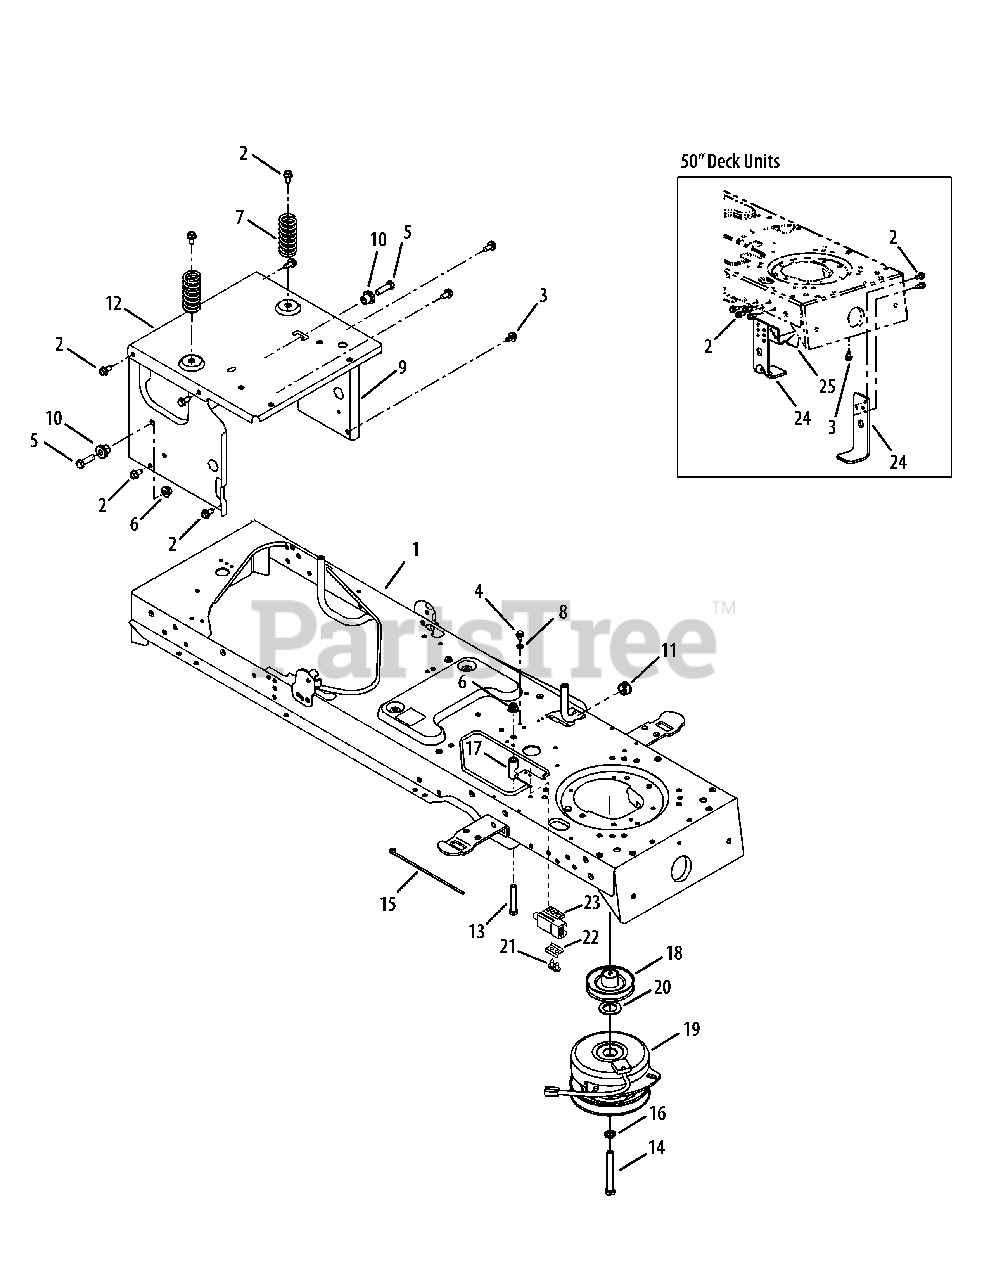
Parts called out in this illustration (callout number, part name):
3	Screw, Hex Wash. Tapp, 5/16-18 x .5
4	Screw, Hex Wash. Hd. Tapp, 1/4-20 x 0.625
5	Hex Screw 3/8-16 x 1.25
6	Nut, Nylon Lock, 3/8-16
7	Spring, Compression, 1.28 OD x 3.125
8	Washer, Lock, Ext. 1/4
11	Snap Bushing
13	Screw, 3/8-16 x 2.25 GR5
14	Screw, Hex Cap , 7/16-20 x 3.5 GR5
15	Cable, Tie, 3/16 x .05 x 7.4
16	Washer, Lock, 7/16, Regular Duty
17	Spacer, 3/8 x 1.54
18	Electric PTO Engine Pulley
19	Clutch, PTO
20	Washer, Flat, 1.031 x 1.62 x .095
21	Screw, #10 - 16, x .500
22	Switch Mounting Plate
23	Interlock Switch
